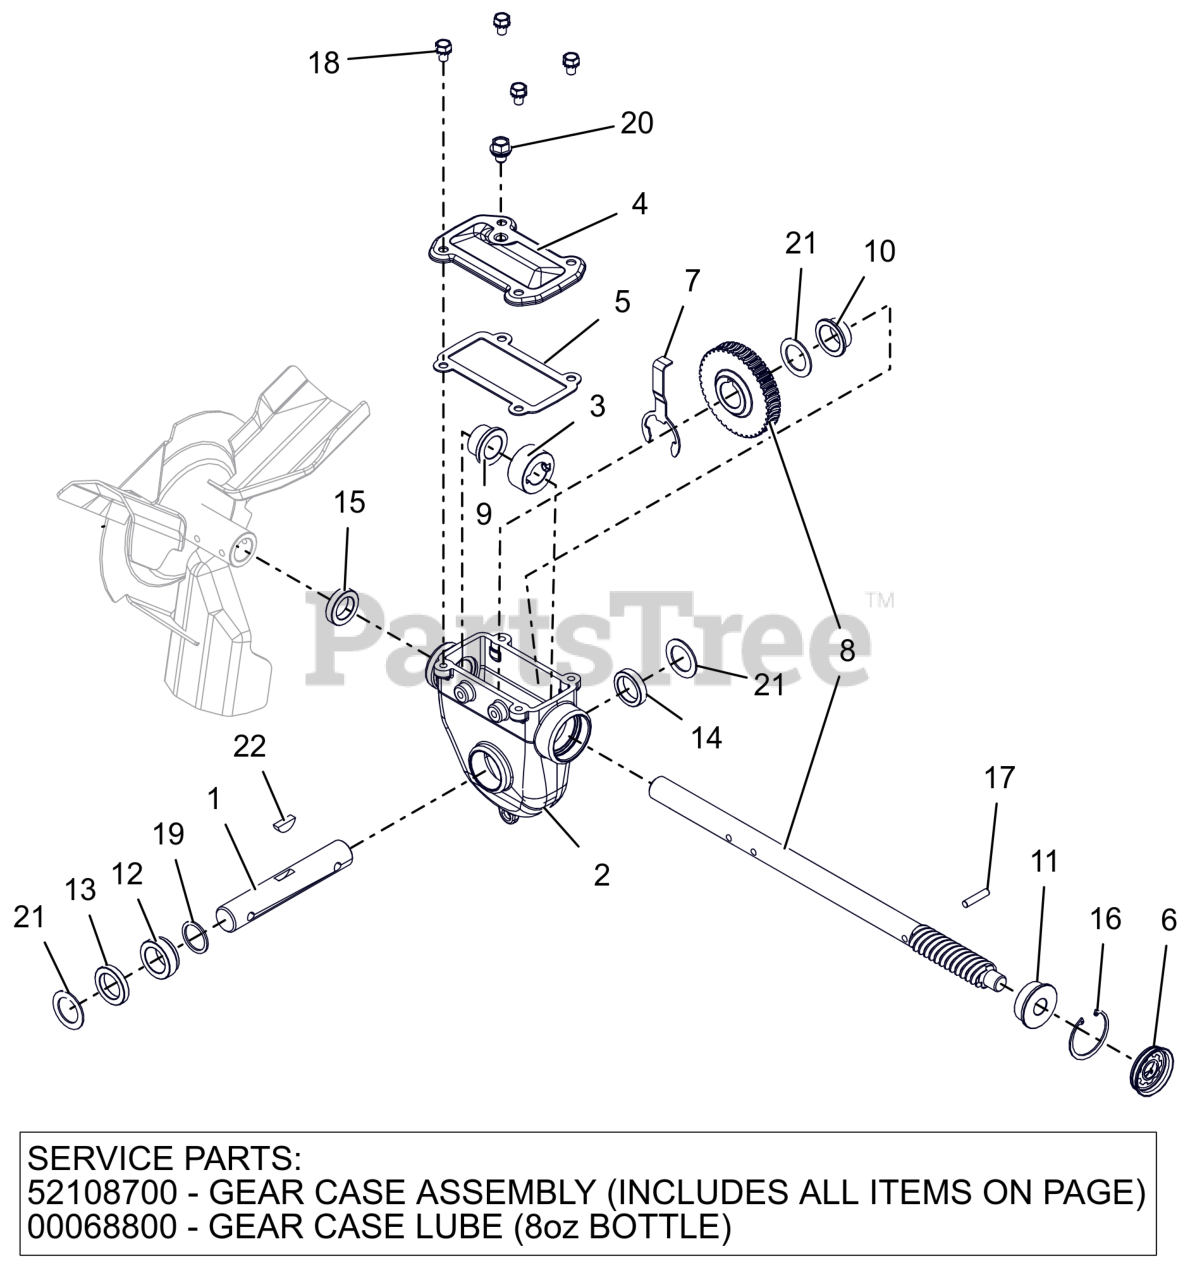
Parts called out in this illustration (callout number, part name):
1	RAKE SHAFT, SHORT-COMMON
2	GEARCASE, LARGE MACHINED
2	KIT, SERVICE - DLX GEAR CASE
3	THRUST COLLAR, .875"ID SLIPFIT
4	COVER, TOP - LARGE IRON
5	GASKET, TOP - LARGE GEARCASE
6	COVER, GEAR CASE 1.75"
7	BUSHING RETAINER, LARGE
8	KIT, SERVICE-WORM SHAFT & GEAR
9	BSHG-FLG .879X1.128X.75X1.45
10	BSHG-FLG 1.006X1.128X.555X1.45
11	BSHG-FLG .628X1.503X.58X1.725
12	BSHG-FLG LARGE, RIGHT
13	SEAL-OIL .999X1.500X.250 TBC29
14	SEAL-OIL .999X1.375X.312 TBC29
15	SEAL-OIL .873X1.375X.312 TBC29
16	RG-RTNG-INT 1.750X.062
17	PIN-STR .250X1.12 6150
18	BLT, SEMS .31-18X.50 G5 ZCC
19	WSHR, FLT 1.010X1.250X.068 ZCC
20	SCR, .380-15X.500 W/SEAL WASHER
21	WSHR, FLT 1.010X1.505X.062 ZCC
22	KEY-WDRF .25X.875 HRD #A
